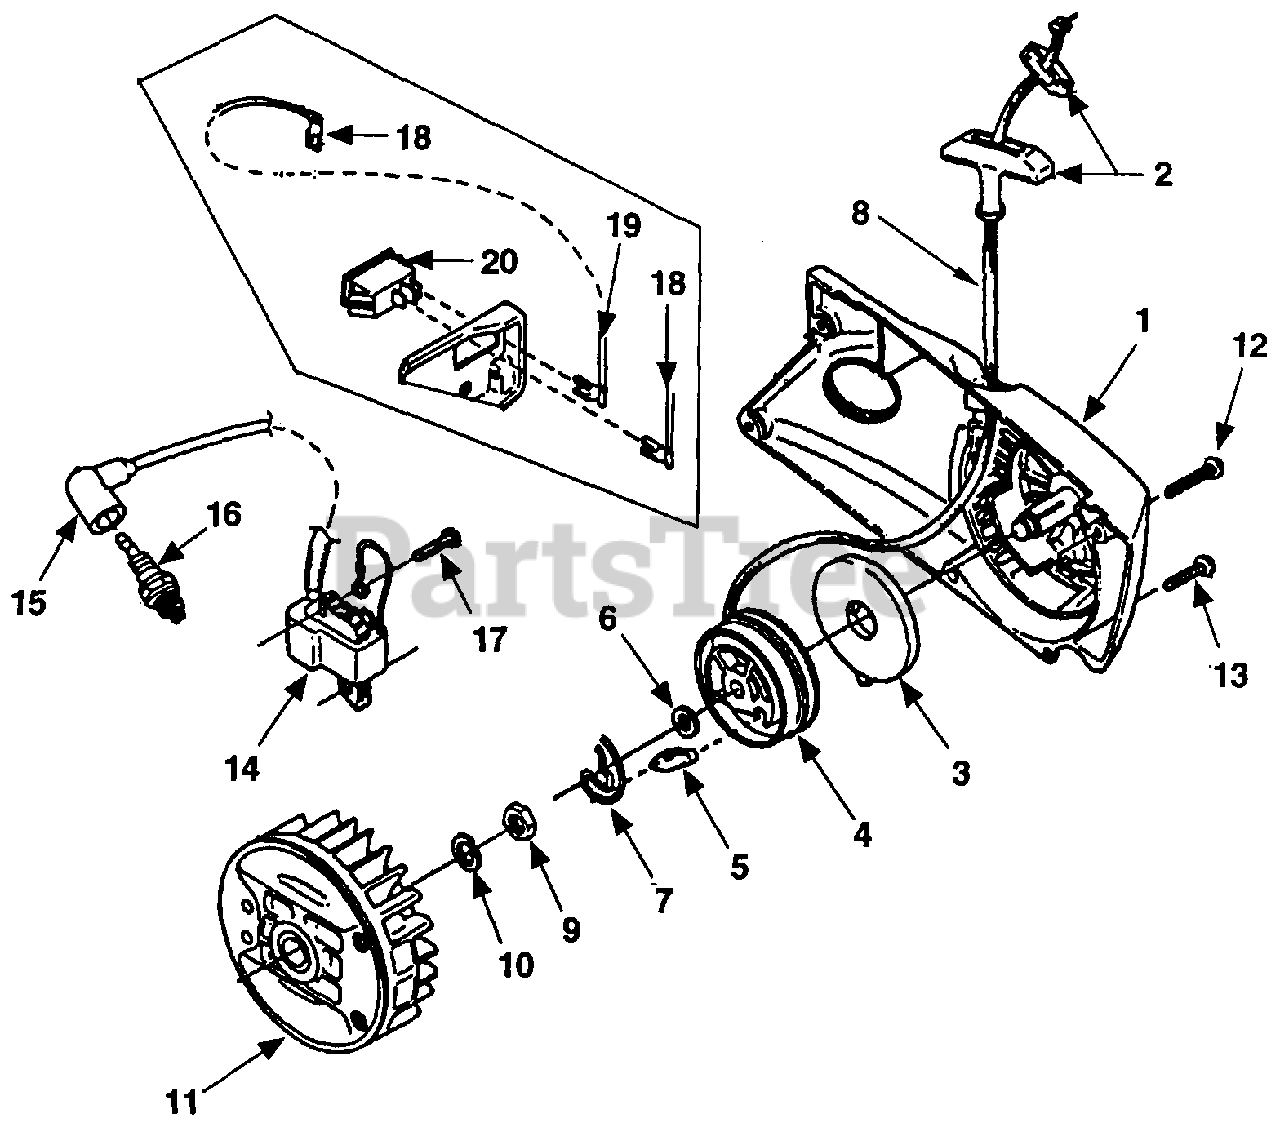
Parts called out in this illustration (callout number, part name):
1	STARTER (Complete)
2	GRIP-Starter (w/insert)
3	SPRING & CONTAINER
4	PULLEY ASSEMBLY
5	WASHER-Thrust
6	PAWL-Starter
7	CLIP-Retainer
8	ROPE-Starter (45")
9	NUT-Jam (3/8 - 24)
10	WASHER-Lock (3/8")
11	ROTOR
12	SCREW-Truss Hd. (10-24 x 1 1/4")
13	SCREW (10-24 x 3/4")
14	IGNITION MODULE
15	SPARK PLUG BOOT KIT
16	SPARK PLUG (CJ6Y)
17	SCREW-Pan Hd (8-32 x 5/8")
18	GROUND WIRE
19	IGNITION GROUND WIRE
20	SWITCH
